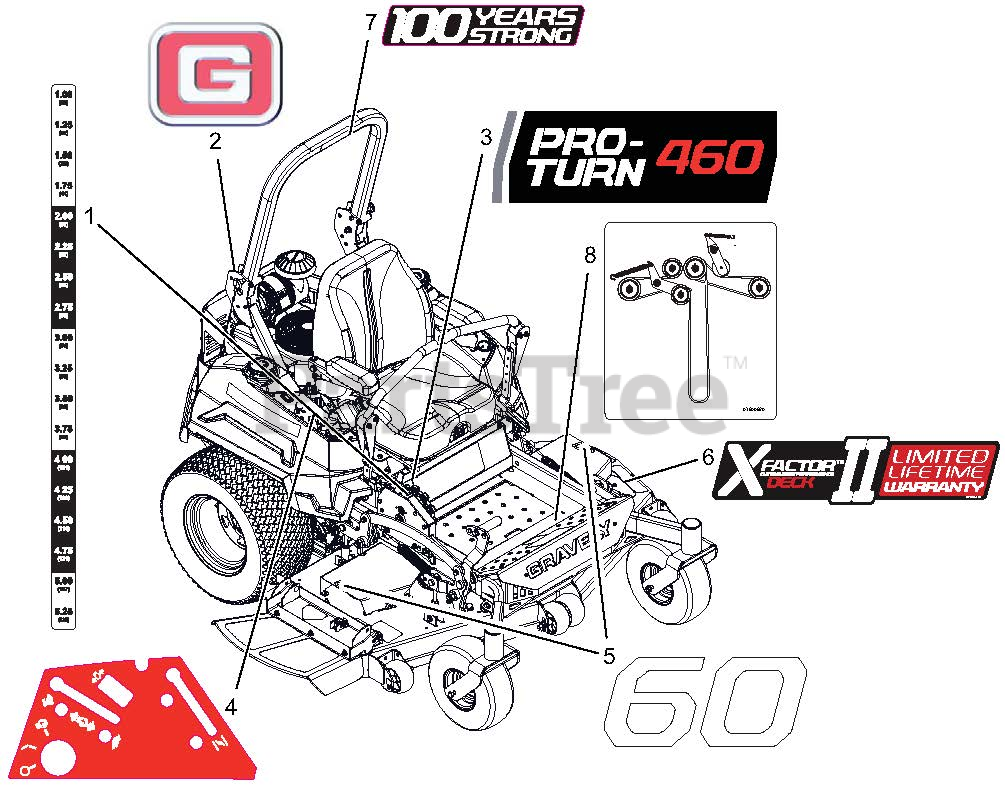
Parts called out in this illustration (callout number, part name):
1	DECAL, PT400 HEIGHT OF CUT
2	DECAL, GRAVELY BRAND
3	DECAL, PRO-TURN 460
4	DECAL, NON-EFI CONTROL PANEL
5	DECAL, 60"
6	DECAL, X-FACTOR DECK
7	DECAL, GRAVELY 100 YEAR
8	DECAL, BELT ROUTE RH BK SIDE IDLER
